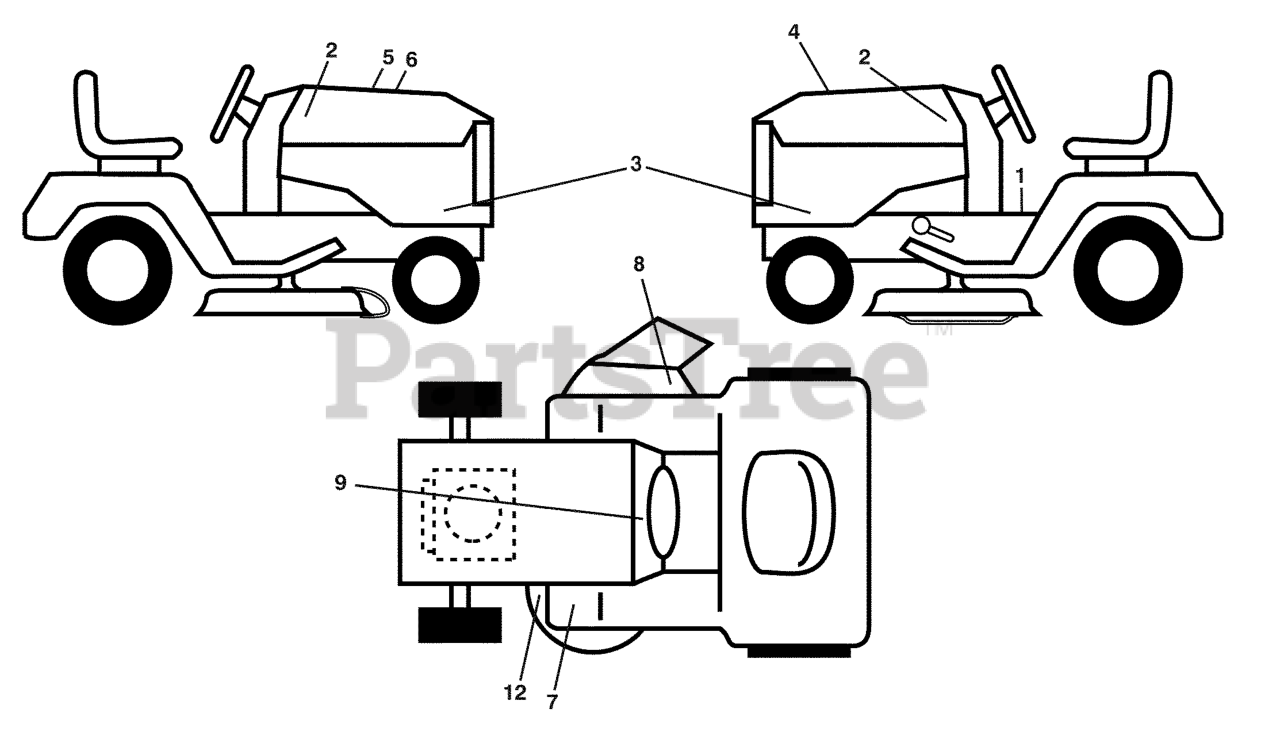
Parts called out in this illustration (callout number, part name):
1	DECAL.FENDER.WARNING.ENG
2	RP EMBLEM, HOOD
3	DECAL.SDPNL.2348LS.ENDUR.HUSQ
4	DECAL.ENG.BSM44.23.ENDUR.27817
5	DECAL.WARNING.CUST.RESP.E85.
6	DECAL.RPL.BSM44.
7	DECAL.PEDAL.HUSQ.CROWN
8	DECAL.WARN.KEEP.HAND.AWAY
9	DECAL BTRY SYMBOLS
12	DECAL.MOWER.SCH.48/54
